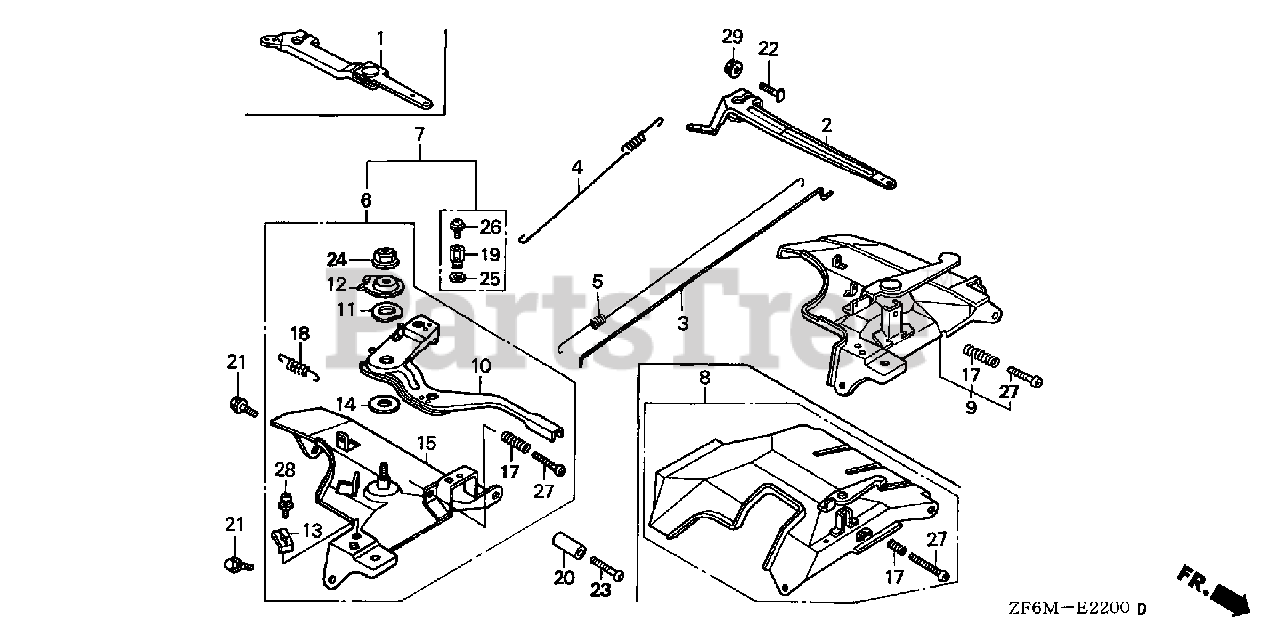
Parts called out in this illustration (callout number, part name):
1	ARM, GOVERNOR
3	ROD, GOVERNOR
4	SPRING, GOVERNOR
5	SPRING, THROTTLE RETURN
8	CONTROL ASSY.
17	SPRING, CONTROL ADJUSTING
21	BOLT, FLANGE (6X12) (CT200)
22	BOLT, GOVERNOR ARM
27	SCREW, PAN (5X35)
29	NUT, FLANGE (6MM)
